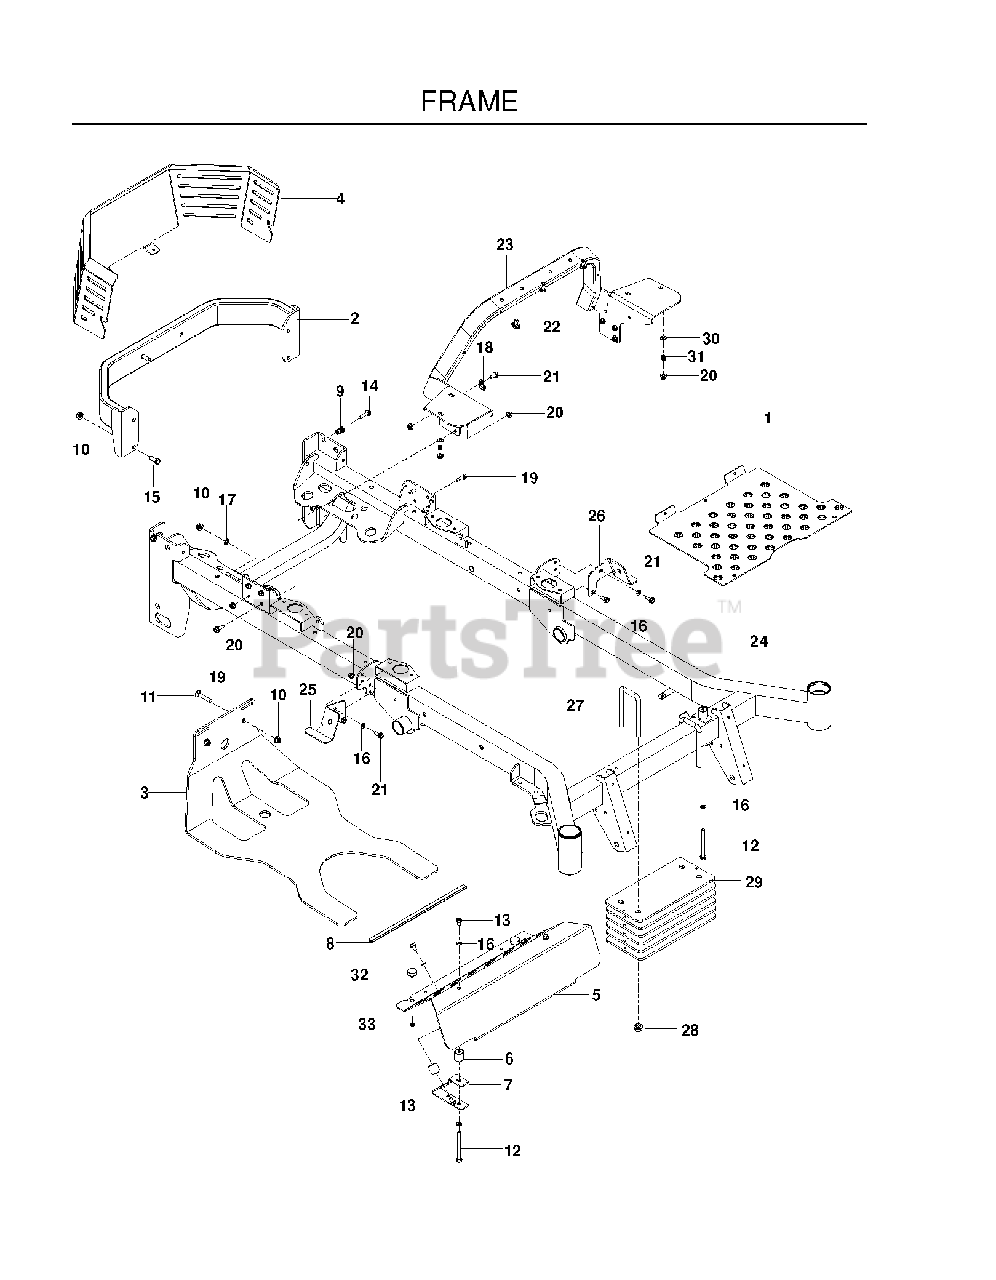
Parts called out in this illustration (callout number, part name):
1	PLATE, FLOOR PAN, BLUE
5	PLATE, FOOTREST, BLUE
6	MOUNT, F/F INSERT
7	BRACKET, REST MOUNT
8	FLEX TRIM, BLACK
9	NUTSERT 5/16-18 THICK GRIP
10	NUT 3/8-16 HEX FLG NYLOC ZD
11	RHSNB 3/8C X 2
12	HHFS 5/16-18 X 3 3/4
13	SCR 5/16-18 X 1/2 SELFTAP ZN
14	HHFS 5/16-18 X 1.25 TPBLT GD 5
15	HCS 3/8C X 1
16	WASH 5/16 DISC SPRING ZD
17	WASHER 3/8 EXT STAR ZD
18	DOUBLE TUBE CLAMP
19	BLT 5/16-18 X 1 THRD FORM ZD
20	5/16-18 NYLOC FLANGE NUT
21	HHFS 5/16-18 X 3/4
22	TIE WRAP, 8-3/8", W/CLIP
24	FRAME, DIESEL, BLUE
25	MOUNT, TANK, RT-BLK
26	MOUNT, TANK, LT-BLK
27	LINKAGE, U-BOLT
28	NUT, 1/2-13 HEX FLG NYLOC ZD
29	PLATE, WEIGHT BLK
30	FLAT WASHER 5/16 SAE
32	BUMPER, 1/4-20 STUD, 1/4
33	JAM NUT 1/4C
